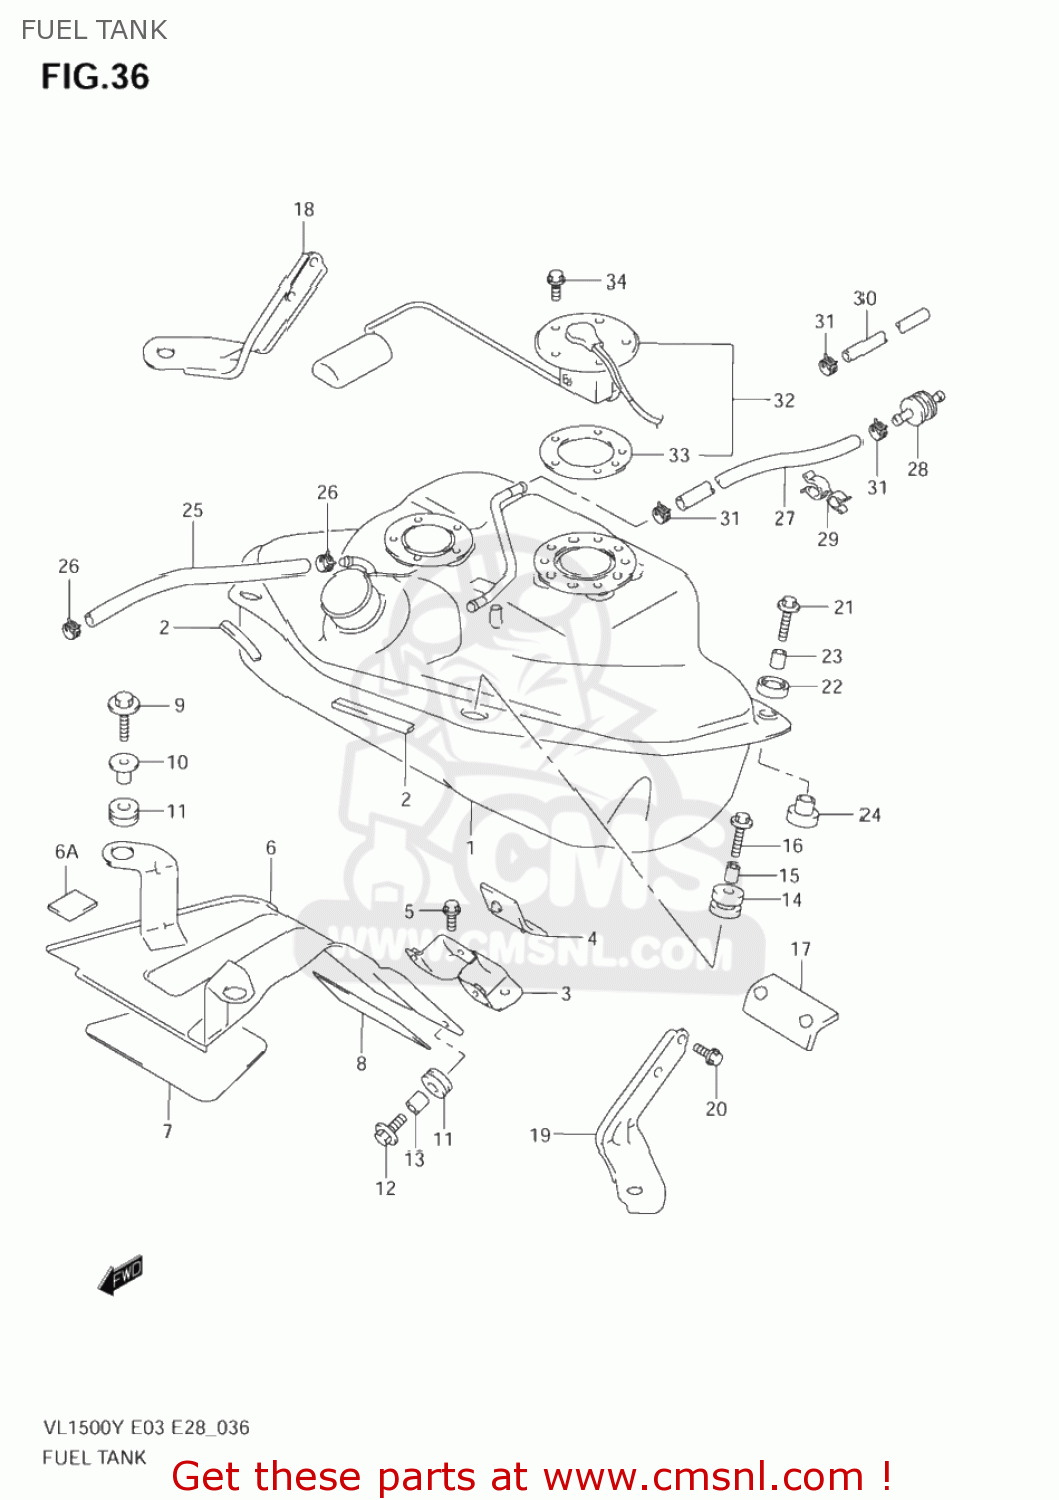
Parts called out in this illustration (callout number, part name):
1	TANK,FUEL
2	MOLDING
3	BRACKET,FUEL TANK FR
4	CUSHION,FUEL TANK FR
5	BOLT
6	COVER,FUEL TANK FR
6A	PAD
7	SHIELD,FR COVER UPR
8	SHIELD,FR COVER LWR
9	BOLT(6X30)
10	WASHER
11	CUSHION
12	BOLT(6X20)
13	SPACER(6.1X8X9.5)
14	CUSHION,FUEL TANK SIDE
15	SPACER(6.5X9X12.5)
16	BOLT(6X25)
17	CUSHION,FUEL TANK RR CTR
18	BRACKET,FUEL TANK RR,R
19	BRACKET,FUEL TANK RR,L
20	BOLT
21	BOLT(6X30)
22	CUSHION
23	SPACER(6.5X9X18)
24	CUSHION
25	HOSE(11X16X600)
26	CLIP
27	HOSE(5.4X11.4X600)
28	VALVE,2WAY CHECK
29	CLAMP
30	HOSE(5.4X11.4X600)
31	CLIP
32	GAUGE ASSY,FUEL LEVEL
33	GASKET,FUEL LEVEL GAUGE (NAS)
34	BOLT 5X10
